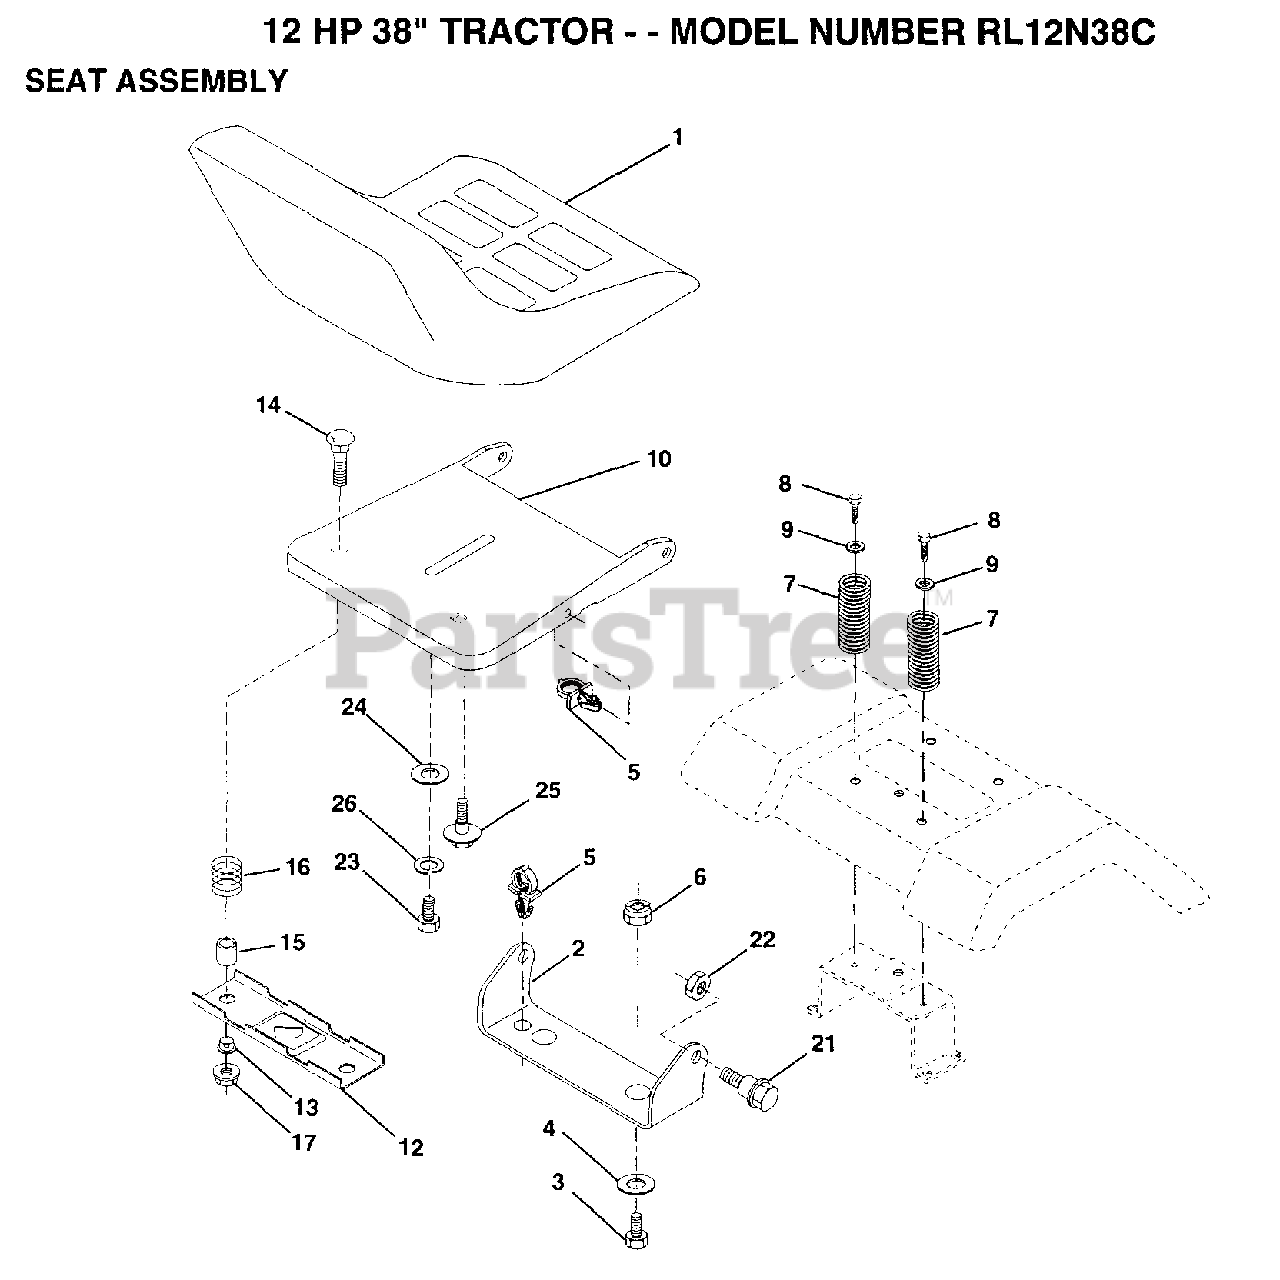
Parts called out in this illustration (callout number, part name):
2	BRACKET PVT SEAT
3	BOLT
4	WASHER PM
5	CLIP PUSH - IN
6	NUT
7	SPRING COMPRESSIO
8	SCREW GTV
9	WASHER
12	BRKT SWITCH
13	BUSHING
15	SPLIT SPACER
16	SPRING
21	BOLT.SHLD.5/16-18
23	BOLT
24	WASHER
25	"BOLT,SHOULDER"
26	LOCKWASHER
